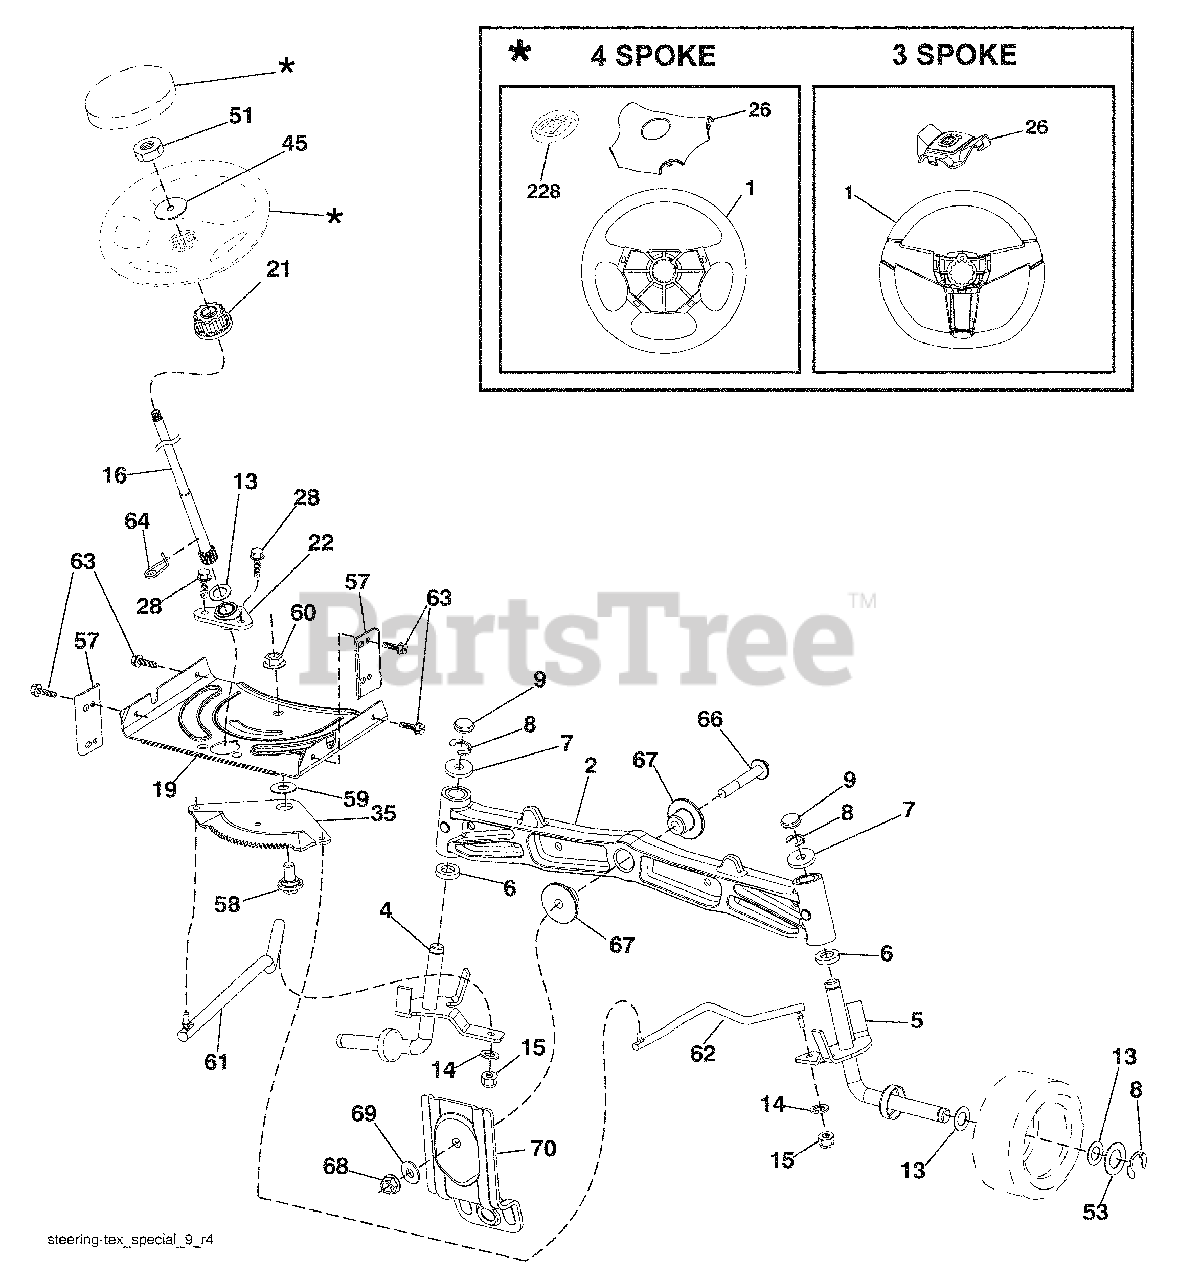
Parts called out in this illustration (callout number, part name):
1	Wheel, Steering
2	Axle Asm., Front
4	Spindle Asm., LH
5	Spindle Asm., RH
6	Bearing, Race Thrust Harden
7	Washer 25/32 x 1-5/8 x 16 Ga.
8	Ring, Clip #T5304-75
9	Cap, Spindle
13	Washer 25/32 x 1-1/4 x 16 Ga.
14	Washer, Lock Hvy Hlcl Spr 3/8
15	Nut, Crown Lock 3/8-24 unf
16	Shaft Steering
19	Plate Steering
21	Adapter, Wheel Steering
22	Bushing, Strg. Blk
26	Insert, Wheel Steering
28	Screw 3/8-16 x 3/4
35	Gear, Sector Plate
45	Washer 9/16 ID x 2-3/8 OD 12 Ga.
51	Nut Hex Jam Toplock 1/2-20 unf
53	Washer Hardened .793 x 1.637 x .060
57	Bracket Upstop
58	Bolt Shoulder Sector Pivot CFM
59	Washer Thrust Sector Steering
60	Nut Flange Lock 5/8-11
61	Draglink, LH
62	Draglink, RH
63	Screw 5/16-18 x 3/4
64	Retainer Clip Spring Steering
66	Bolt Hex Fghd 7/16-14 x 3 Serr
67	Bushing PM Front Axle
68	Nut Lock Flange 7/16-14 Gr. 5
69	Washer 1.5 x .505 x .118
70	Bracket Deck Susp. Front
228	Decal Wheel Steering
